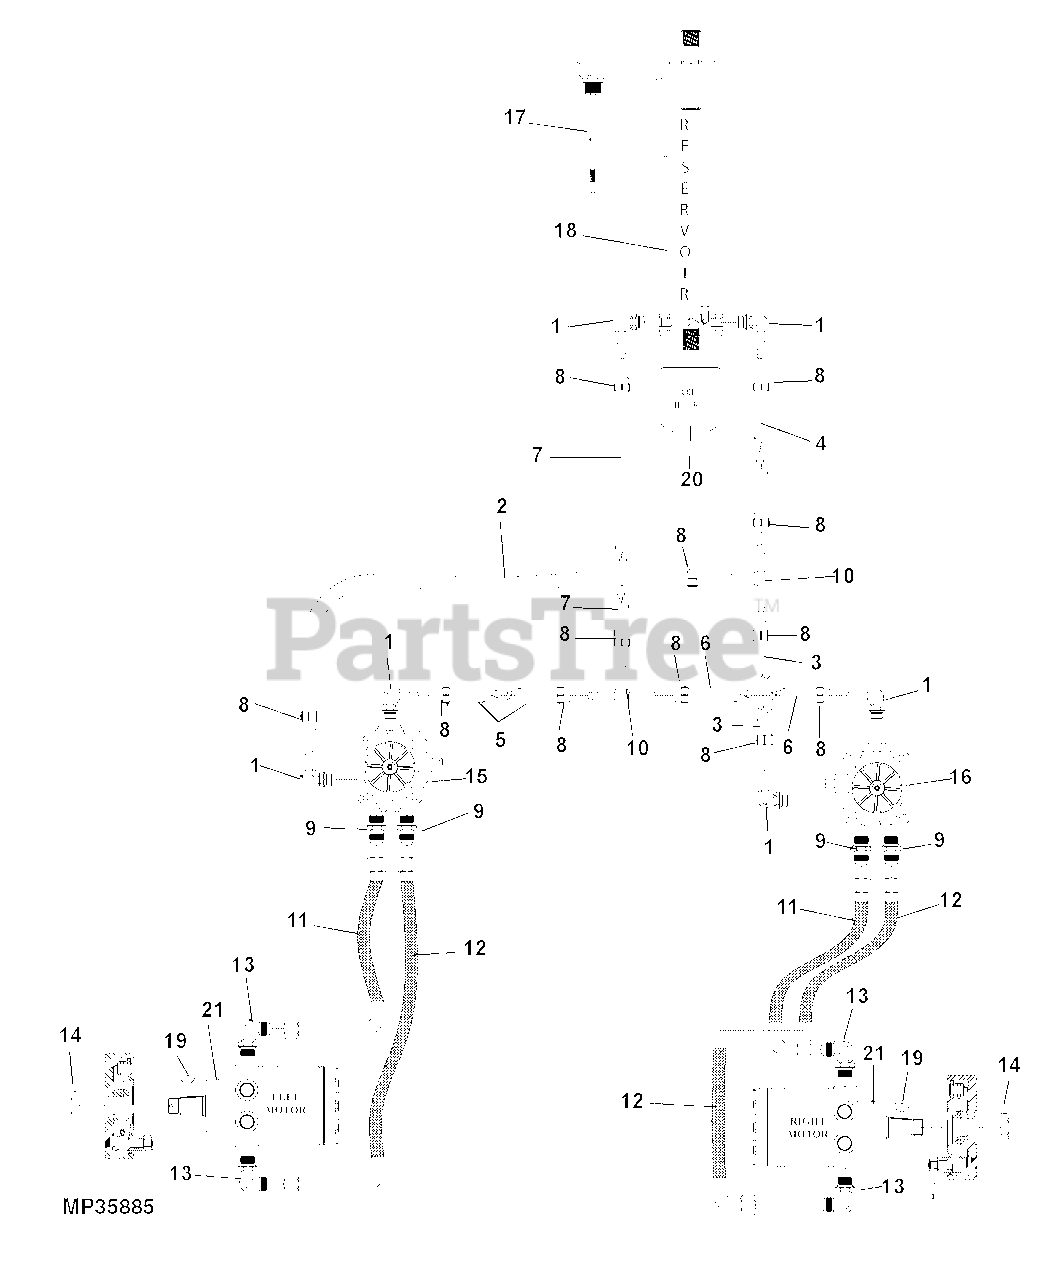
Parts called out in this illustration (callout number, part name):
1	FTG, 90 9/16MOR X 3/8HOSE
8	CLAMP, HOSE - 1/2" PINCH
9	FITTING, STRAIGHT
10	FTG, TUN 3/8 HOSE
11	HOSE, HYDRO
12	HOSE
13	FTG, 7/8ORB X 3/4JIC X 90
14	NUT, W/LOCKING PATCH
15	PUMP, HYDRO
16	PUMP, HYDRO
17	CAP, FILLER, OIL
18	RESERVOIR, HYDRAULIC
19	KEY, 5/16 X 3/4 WOODRUFF #B
20	FILTER, OIL
21	MOTOR, RH HYDRO-GEAR WHEEL
